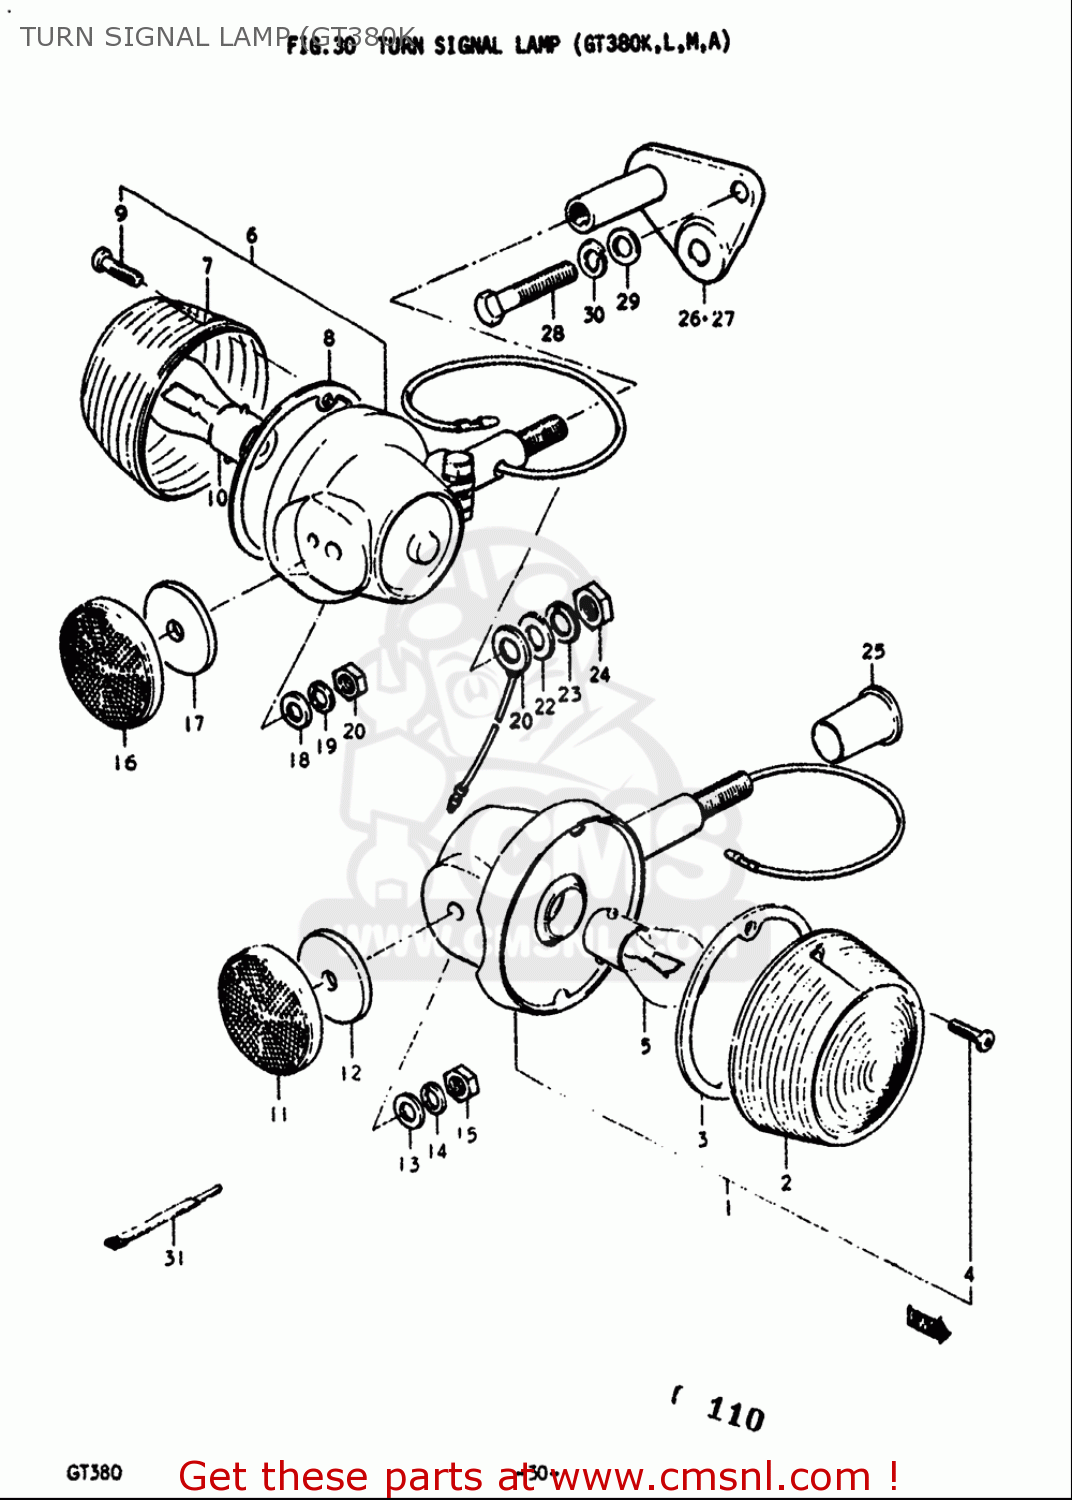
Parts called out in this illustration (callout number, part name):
2	LENS
3	GASKET,TURNSIGNAL LENS (NAS)
4	SCREW
5	BULB(12V23W,STANLEY,A4577A)
7	LENS
8	GASKET,TURNSIGNAL LENS (NAS)
9	SCREW
10	BULB(12V23W,STANLEY,A4577A)
11	REFLEX REFLECTOR,RR
13	WASHER(5.5X18X1)
14	WASHER,LOCK
15	NUT
18	WASHER(5.5X18X1)
19	WASHER,LOCK
20	NUT
21	LEAD WIRE
22	WASHER
23	WASHER,LOCK
24	COVER,FRONT TURN SIGNAL BRACKET
25	NUT
26	BRACKET, REAR TURN SIGNAL RH
28	BOLT
29	WASHER
30	WASHER,LOCK
31	CLAMP
